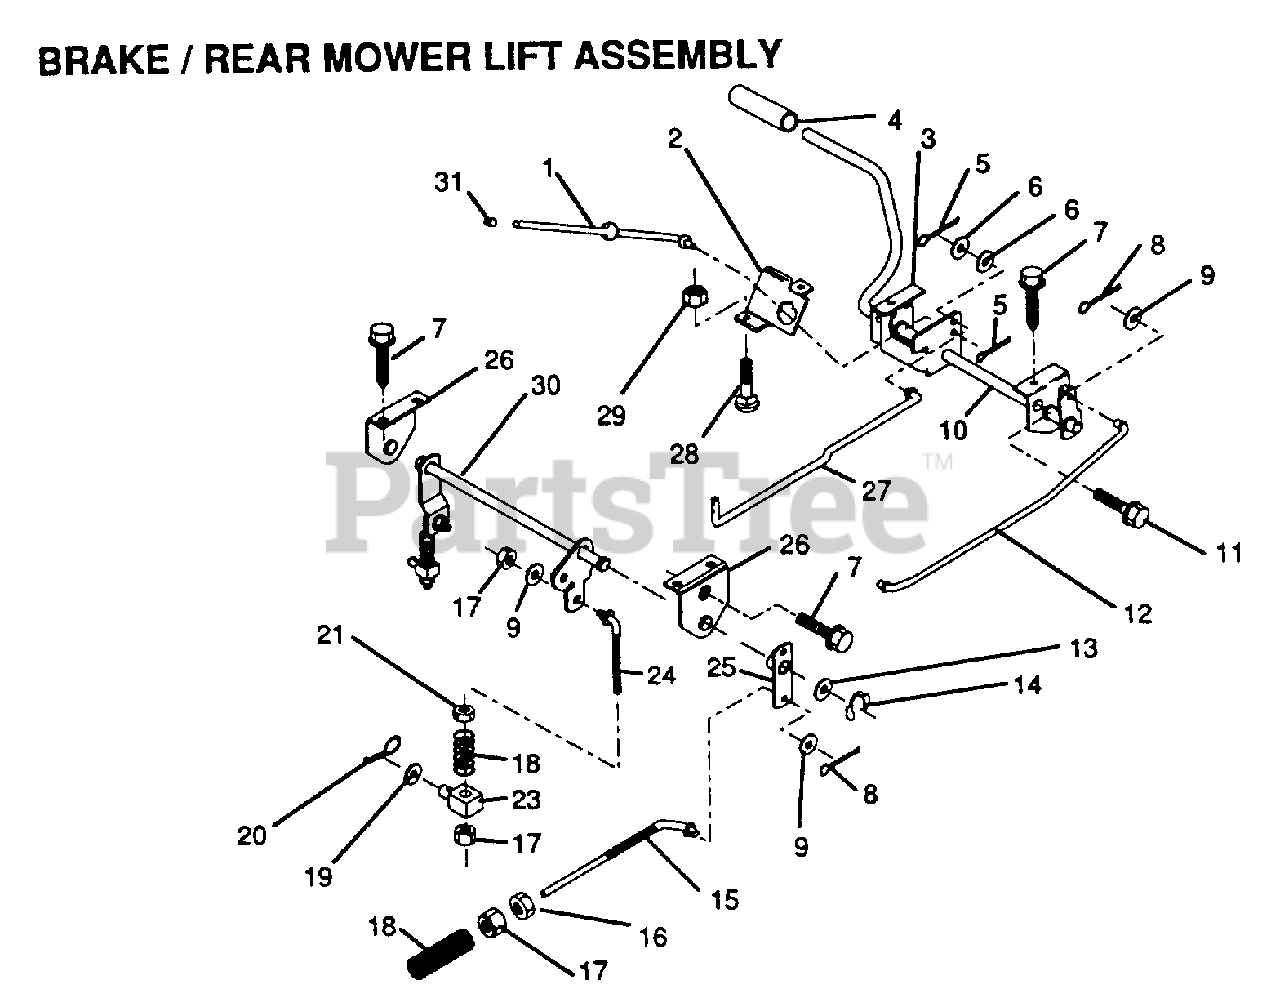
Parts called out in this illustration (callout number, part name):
1	"ROD,PARK BRAKE"
2	"BRKT,PARK BRAKE"
3	"BRKT,CLU PEDAL LH"
4	PEDAL COVER T
6	WASHER
7	SCREW LT
8	COTTER PIN
9	WASHER
11	SCREW LT
12	"ROD,FRT BRAKE"
13	WASHER T
14	KLIP RING
16	NUT
18	SPRING ROD LT
19	WASHER
20	SPRING.RETAINER
21	LOCKNUT
22	SPRING ROD LT
24	"LINK.LIFT.3.5"""
25	BRAKE PIVOT ARM
26	"BRKT,LIFT SHAFT"
27	"ROD,CLUTCH"
30	REAR MOWER LIFT
31	PLUNGER CAP T
